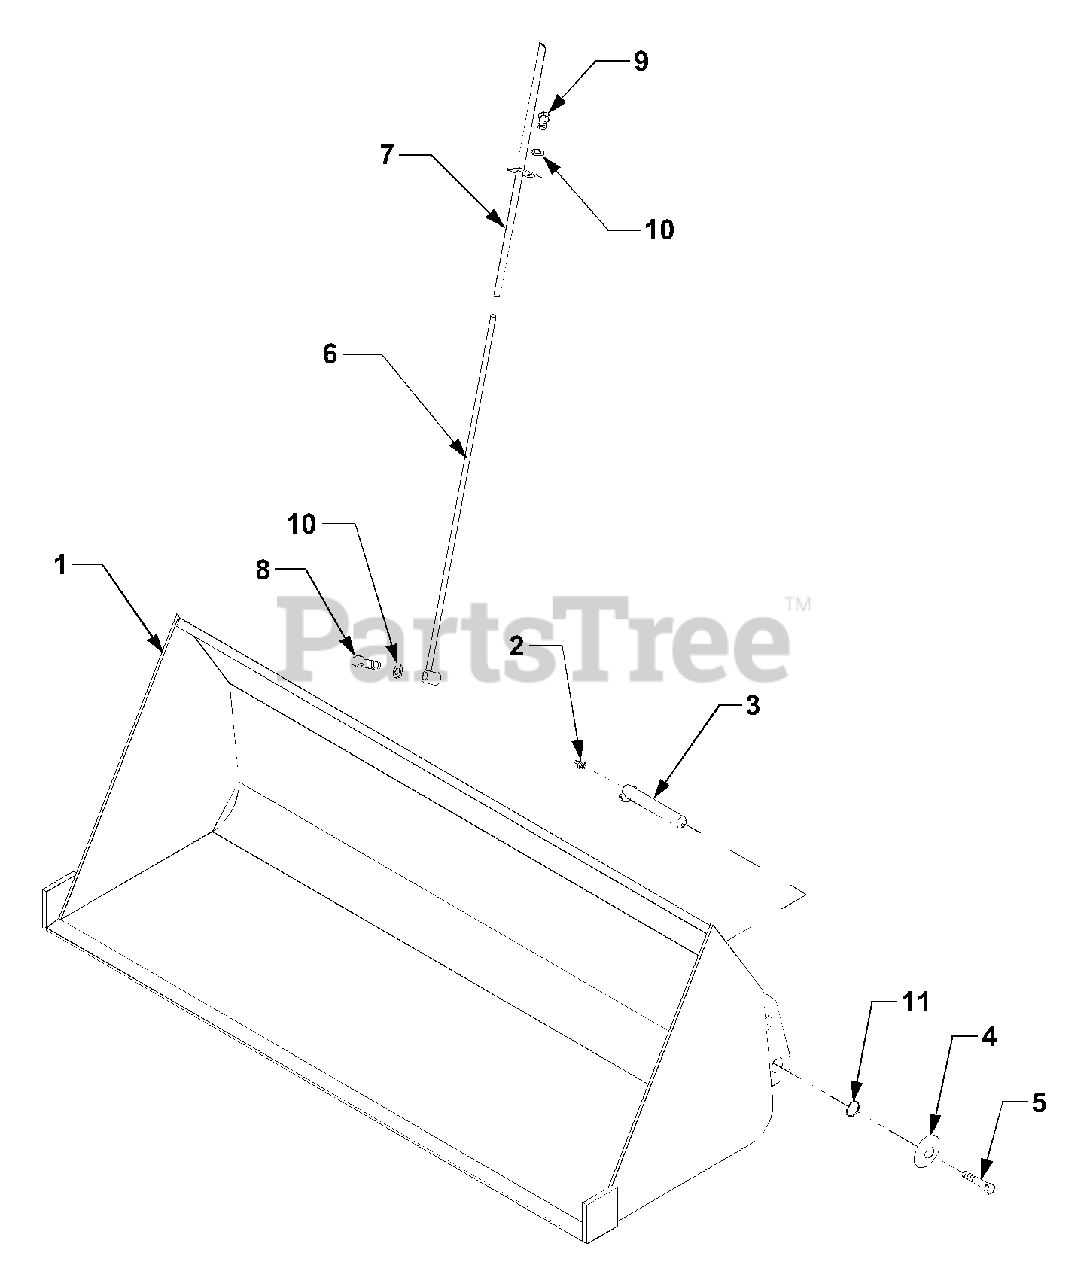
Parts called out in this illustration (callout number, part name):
1	Bucket Assembly, 72"
2	Grease Fitting
3	Pivot Pin, 1" x 103mm
5	Hex Cap Screw, 5/16" x 3/4"
6	Bucket Level Indicator Rod
7	Indicator Rod Tube
8	Hex Cap Screw, 5/16" x 1"
9	Hex Cap Screw, 5/16" x 1/2"
10	Lock Washer, 5/16"
